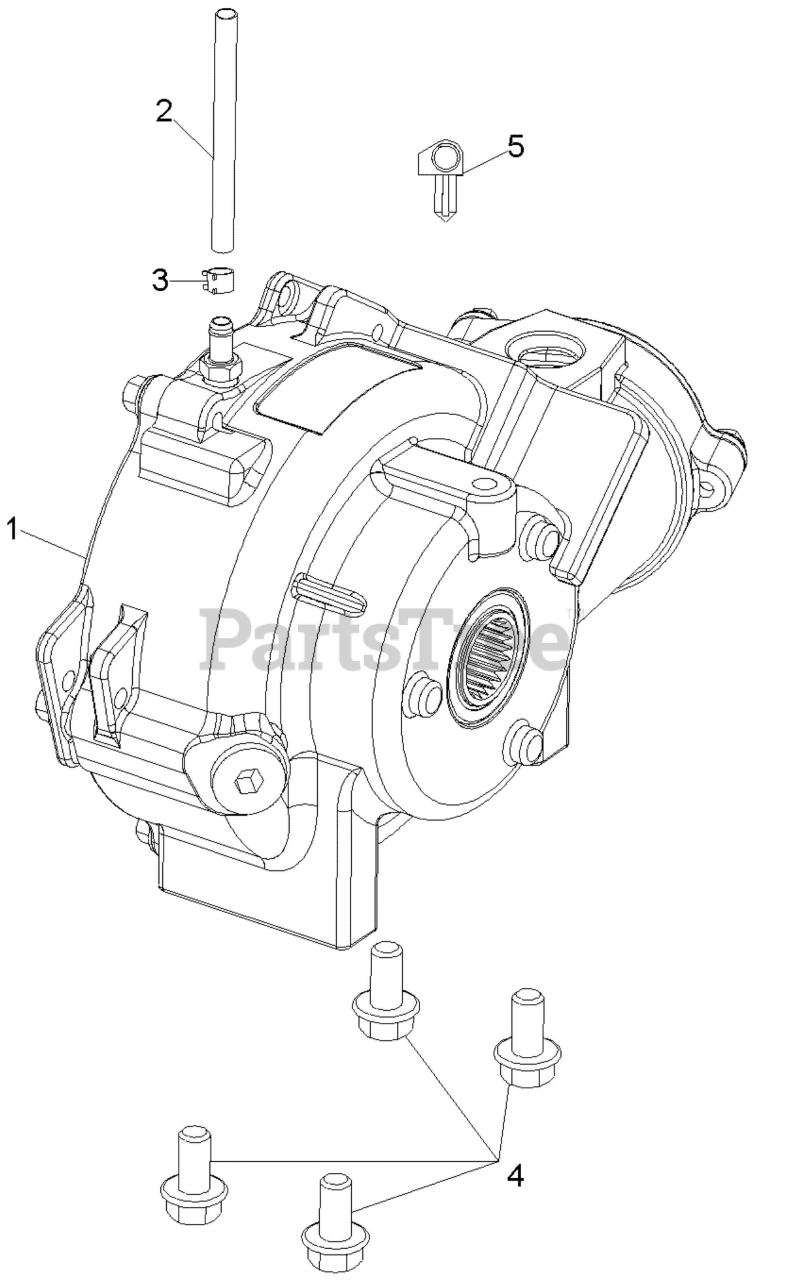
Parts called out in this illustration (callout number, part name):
1	ASM-GEARCASE,FRONT
2	LINE-BOOST,3/16 ID,76CM
3	CLAMP,HOSE(10)
4	BOLT-M10X1.5X20,HXFLG,W/PATCH
5	CLIP,ROUTING,.472 B.D.,HINGED
